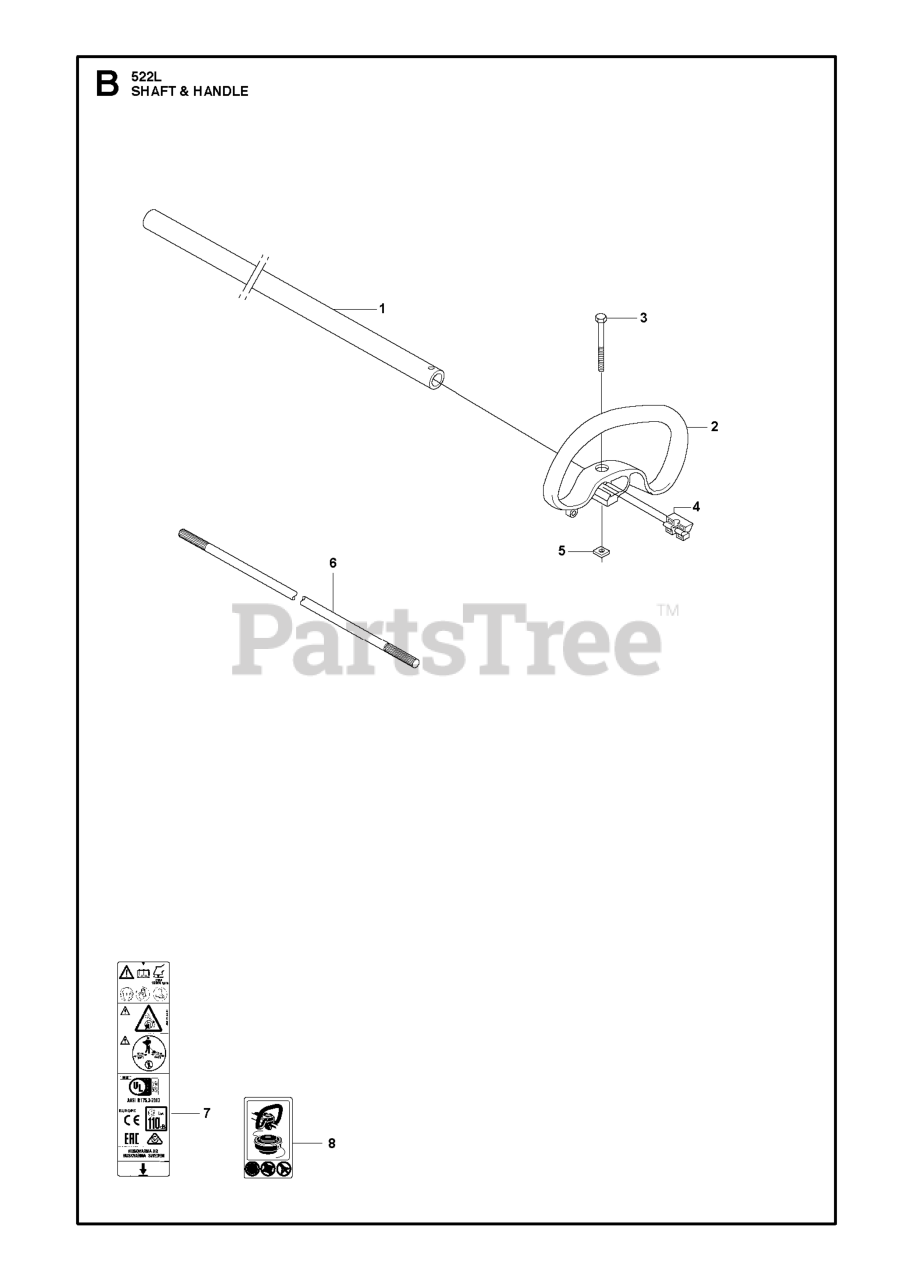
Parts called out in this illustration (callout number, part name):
1	TUBE
4	SPACER PLASTIC
6	DRIVESHAFT 525L
7	DECAL WARNING
8	DECAL WARNING "NO BLADES"
